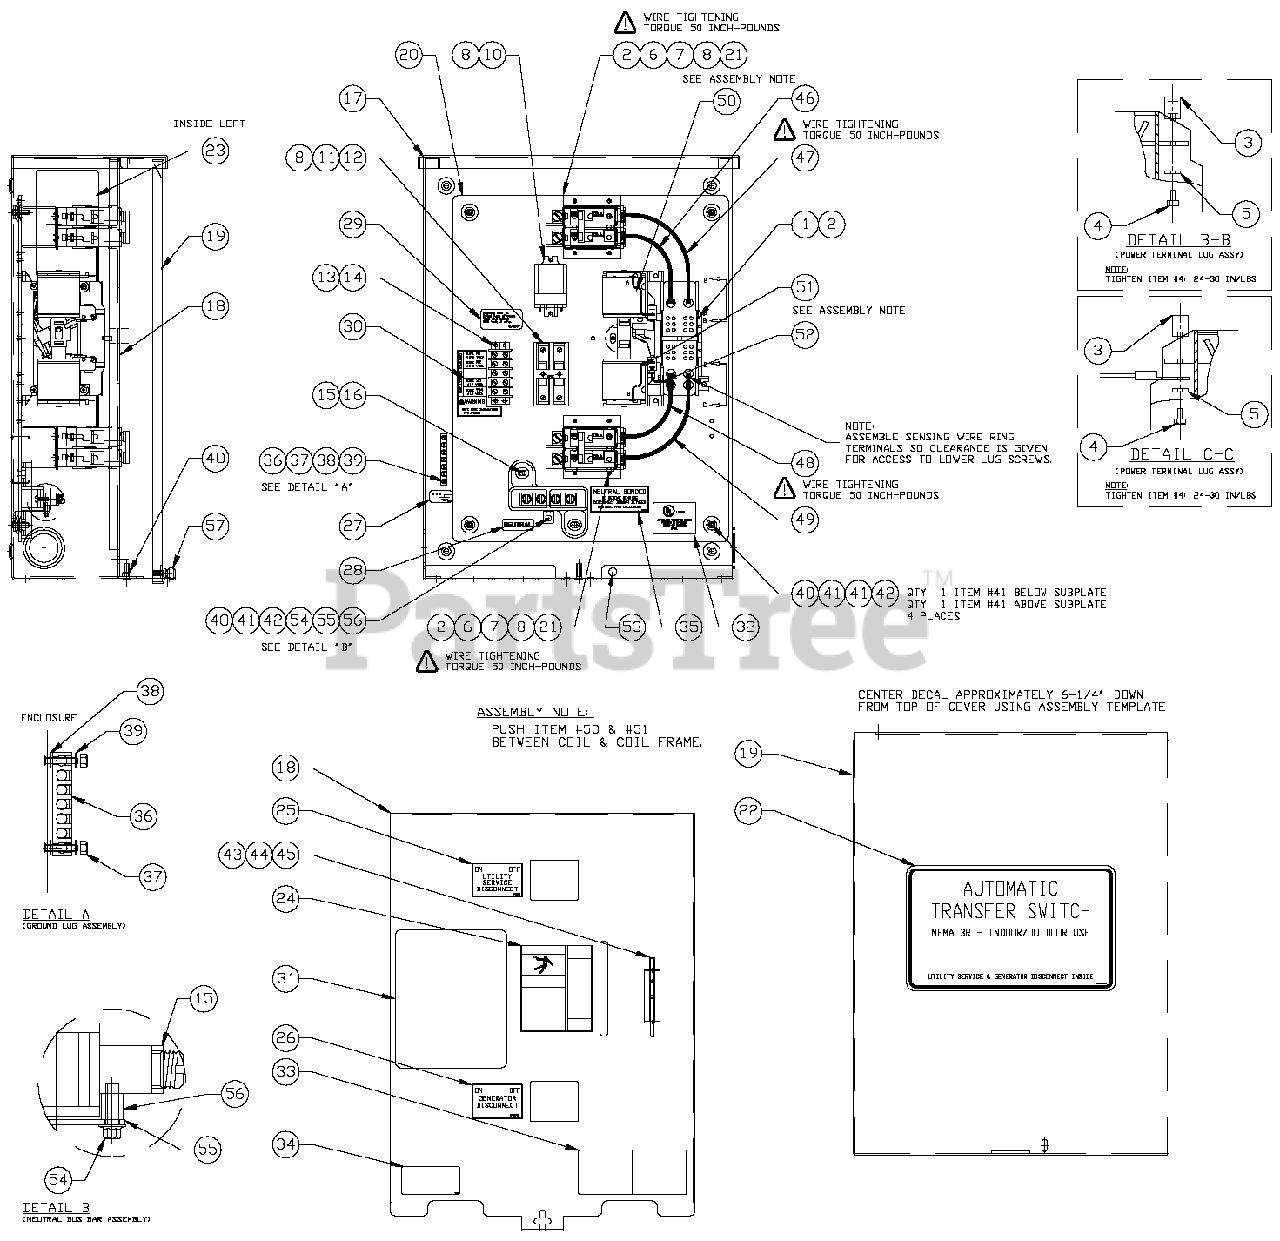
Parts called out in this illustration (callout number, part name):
1	TR SW-HSB 100A 2P 250V
2	SCREW HHTT M5-0.8 X 10 BP
3	LUG SLDLSS 1/0-#14X9/16 AL/CU
4	SCREW, PPHMS 10-32 X 3/8" "
5	WASHER, LOCK # 10
6	CB 100A 2P BACK MNT SIEMENS
7	C/BKR MOUNTING BRACKET
8	SCREW PHTT M4-0.7 X 12 ZYC
10	RELAY PNL 12VDC DPDT
11	FUSEBLOCK 30A 600V 2 POLE
12	FUSE 5A X BUSS HLDR73591
13	BLOCK, TERM 20A 5 X 6
14	RIVET, POP .156 X .67
15	ASSY-NEUT BLK 100A W/TAP
16	SCREW HHTT M6-1.0 X 12 MM
17	ENCLOSURE, 100/200A TRANSFER SWITCH
18	COVER, INSIDE TRANSFER SWITCH ENCL
19	COVER, TRANSFER SWITCH
20	SUBPLATE, 100/200A XFER SW
21	RISER, 100A SERVICE ENTRANCE
22	DECAL, FRNT CVR ATS 3R SER DIS
23	DECAL, XFER SW SE 100A 120/240
24	DECAL, MANUAL OPERATING HANDLE
25	DECAL, UTILITY DISCONNECT
26	DECAL, GENERATOR DISCONNECT
27	DECAL, GROUNDING LUG
28	DECAL, NEUTRAL
29	DECAL, FUSE REPLACEMENT
30	DECAL, TERMINAL STRIP
31	DECAL, TEST SEQUENCE
32	DECAL, UL LIST HSB
33	DECAL, TERMINAL SHOCK HZD BI
34	DECAL, LIVE CIRCUIT ENG/FRN/SPN
35	DECAL, NEUTRAL CONNECTION
36	GROUND BAR (5) 4-14 AWG CONN
37	NUT HEX LOCK M4-0.7 SS NYL INS
38	WASHER SHAKEPROOF EXT #8 STEEL
39	WASHER FLAT M4
40	NUT HEX 1/4-20 SS
41	WASHER FLAT 1/4-M6 ZINC
42	WASHER LOCK M6-1/4
43	BRACKET, ARM EXTENDER
44	RIVET POP .156 X .362 AL
45	ARM EXTENDER PIN
46	WIRE ASM, 2AWG 100A 2-P T/S N1A
47	WIRE ASM, 2AWG 100A 2-P T/S N2A
48	WIRE ASM, 2AWG 100A 2-P T/S E1A
49	WIRE ASM, 2AWG 100A 2-P T/S E2A
52	WIRE-E1
53	NUT TRIC 1/4-20 X .525
54	SCREW HHTT #8-32 X 1/2 CZ
55	BUSBAR, NEUTRAL BLOCK
56	5/16" BRASS SPACER
57	THUMB SCREW 1/4-20x1/2
